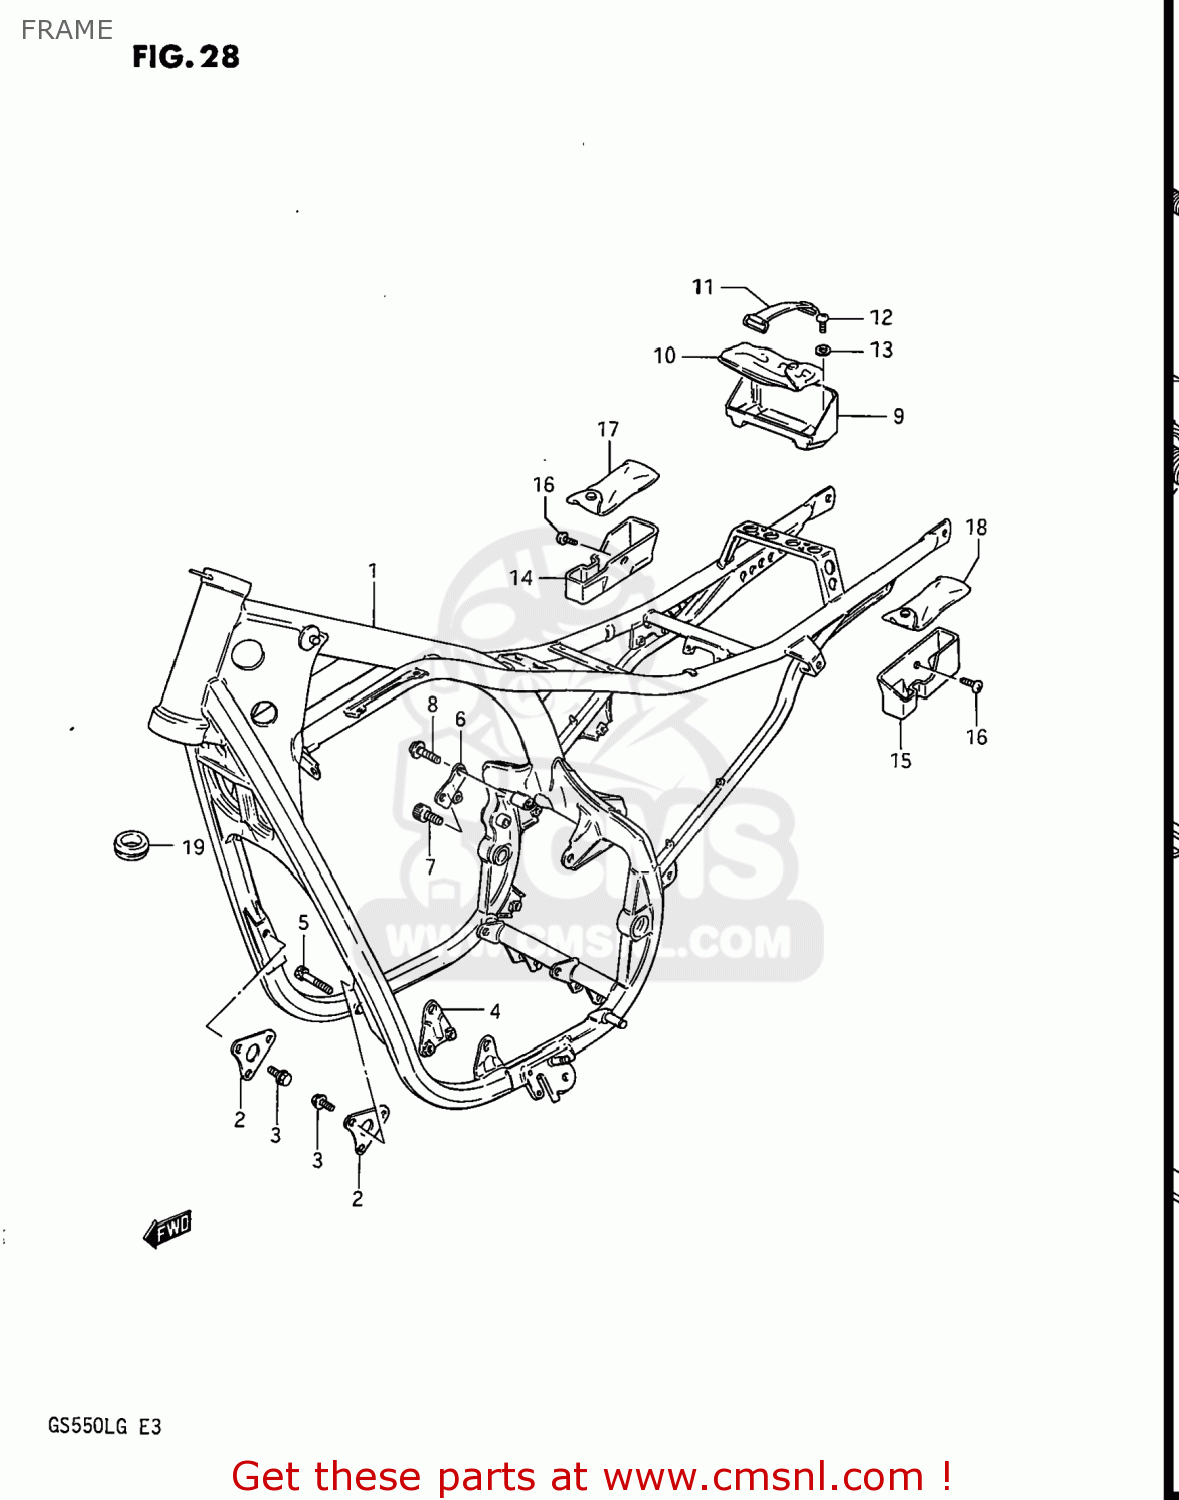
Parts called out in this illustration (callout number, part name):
1	FRAME
2	PLATE,ENGINE MOUNTING
3	BOLT, LOWER
4	PLATE,ENGINE MOUNTING
5	BOLT 8X45
6	PLATE,ENGINE MOUNTING NO.4
7	BOLT 8X45
8	BOLT, LOWER
9	HOLDER,TOOL
10	TOOL ASSY
11	BAND
12	SCREW 6X12
13	WASHER
15	HOLDER,TOOL
16	SCREW 6X12
17	TOOL ASSY
19	GROMMET
